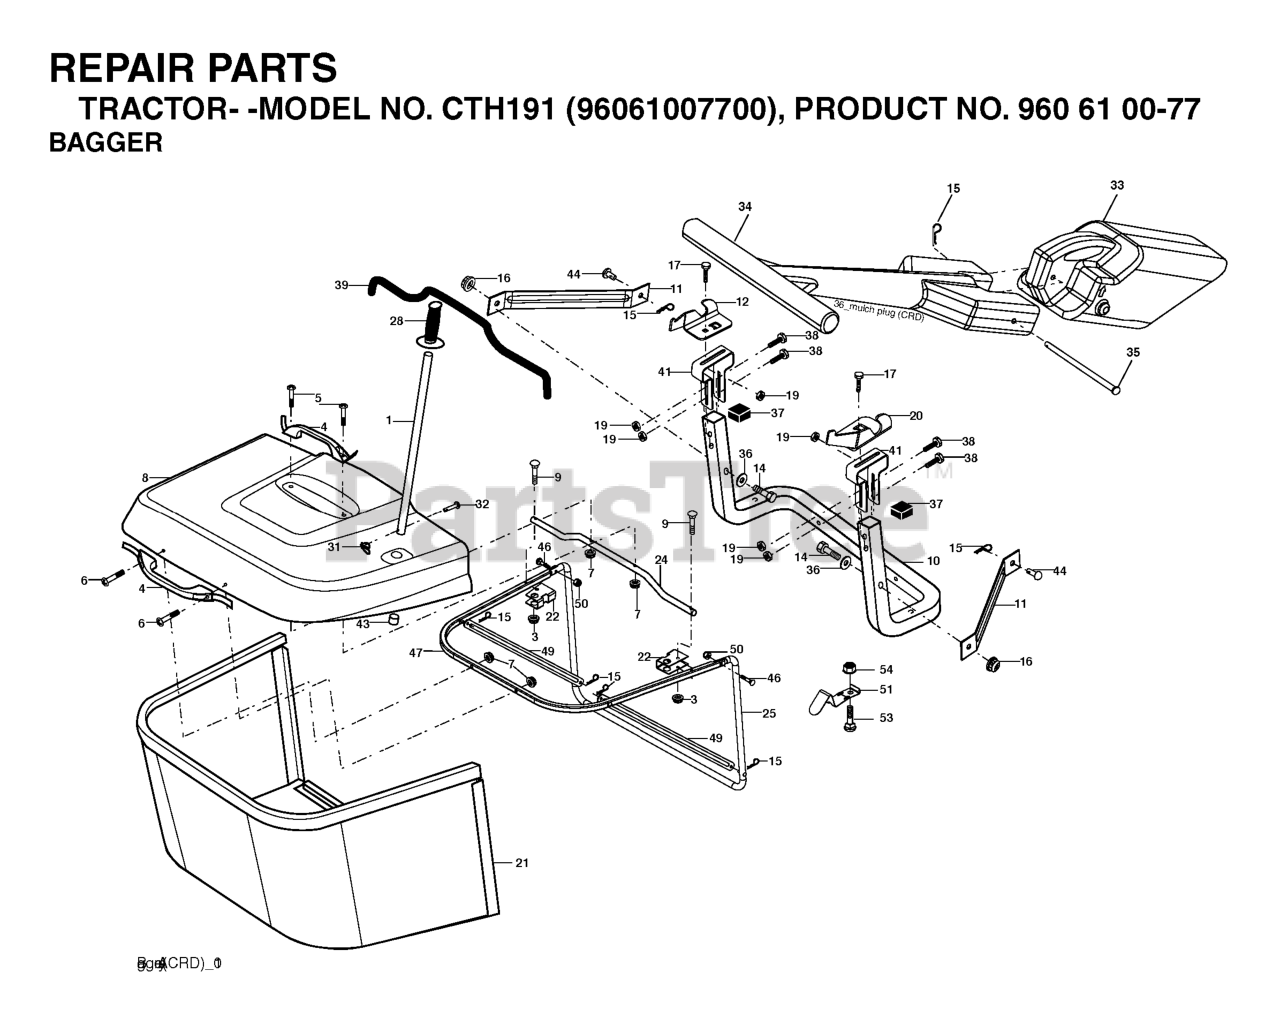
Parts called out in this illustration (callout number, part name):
1	TUBE HANDLE
3	NUT T
4	HANDLE.BAGGER.W/LVRS.BLK.CRD
5	SCREW.PAN.HEAD
6	REPL BY 532 75 00-29
8	COVER.PNT.BGR.CRD.WSLOTS.MS668
9	Bolt Carriage 1/4-20 x 2.25d x Gr.5
10	TUBE
11	BRACKET.SUPPORT.UPPER.BAG.CRD
12	BRKT PIVOT
14	BOLT-HEX EAK
15	RETAINER-SPRNG RB
16	NUT LOCK FLG 3/8-16 UNC
17	RP BOLT 5/16-18 X3/4 ZN/YEL GR
19	NUT LOCK HEX FLANGE 5/16-18
20	BRKT.PIVOT.RH.CRD
22	BRKT.SIDE.BAG.CRD
24	TUBE.PIVOT.BAG.CRD.BLACK
25	PIPE
26	TUBE.LOWER.BAG.CRD
28	GRIP.HANDLE.BLACK
31	RETAINER CLIP
32	RIVET,DRILLED
33	MULCH PLUG, CTH150
34	HANDLE.MULCHER.92.CRD (2 2)
36	WASHER
37	Plug Support Bagger CRD
38	BOLT.5/16-18X2.5
39	SEAL.TRIM.37'
41	BRKT.VERT.ADJ.BAGGER.CRD
43	PLUG, TUBING END
46	BOLT.CARRIAGE.5/16-18
47	PIPE
49	ROD
50	NUT.71038.31-18.HEX.NYLOCK
51	LATCH
53	NUT
54	BOLT
